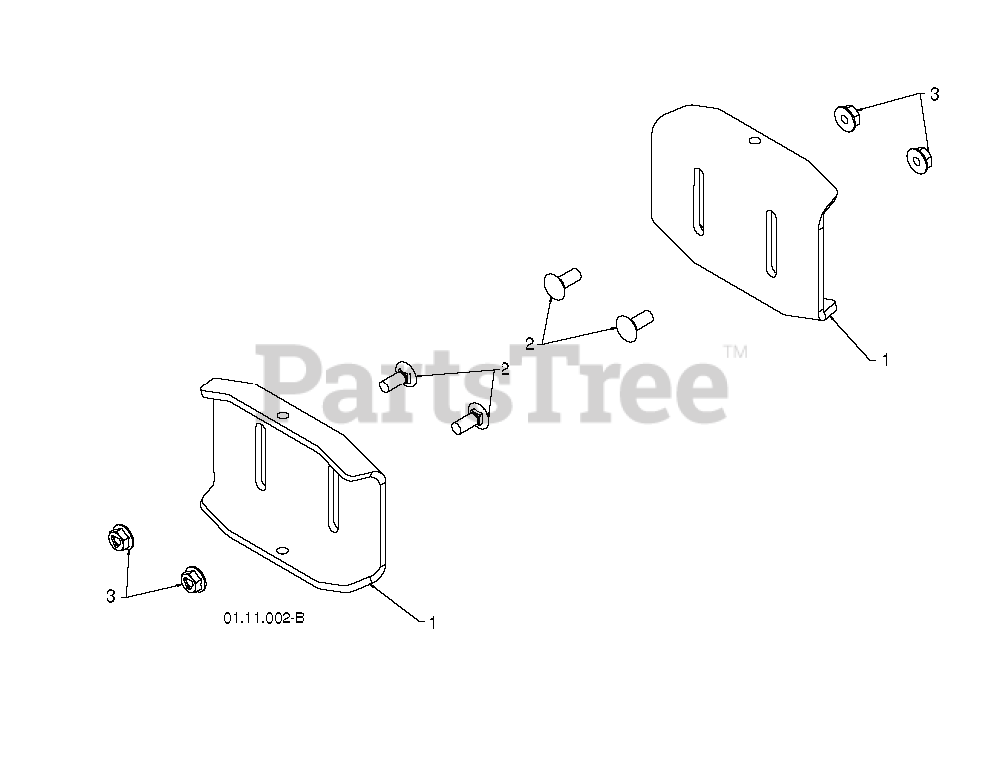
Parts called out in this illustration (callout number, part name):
1	PLATE.SKID.HEAVYDUTY.BLACK
2	BOLT
3	NUT.LOCK.5/16-18
